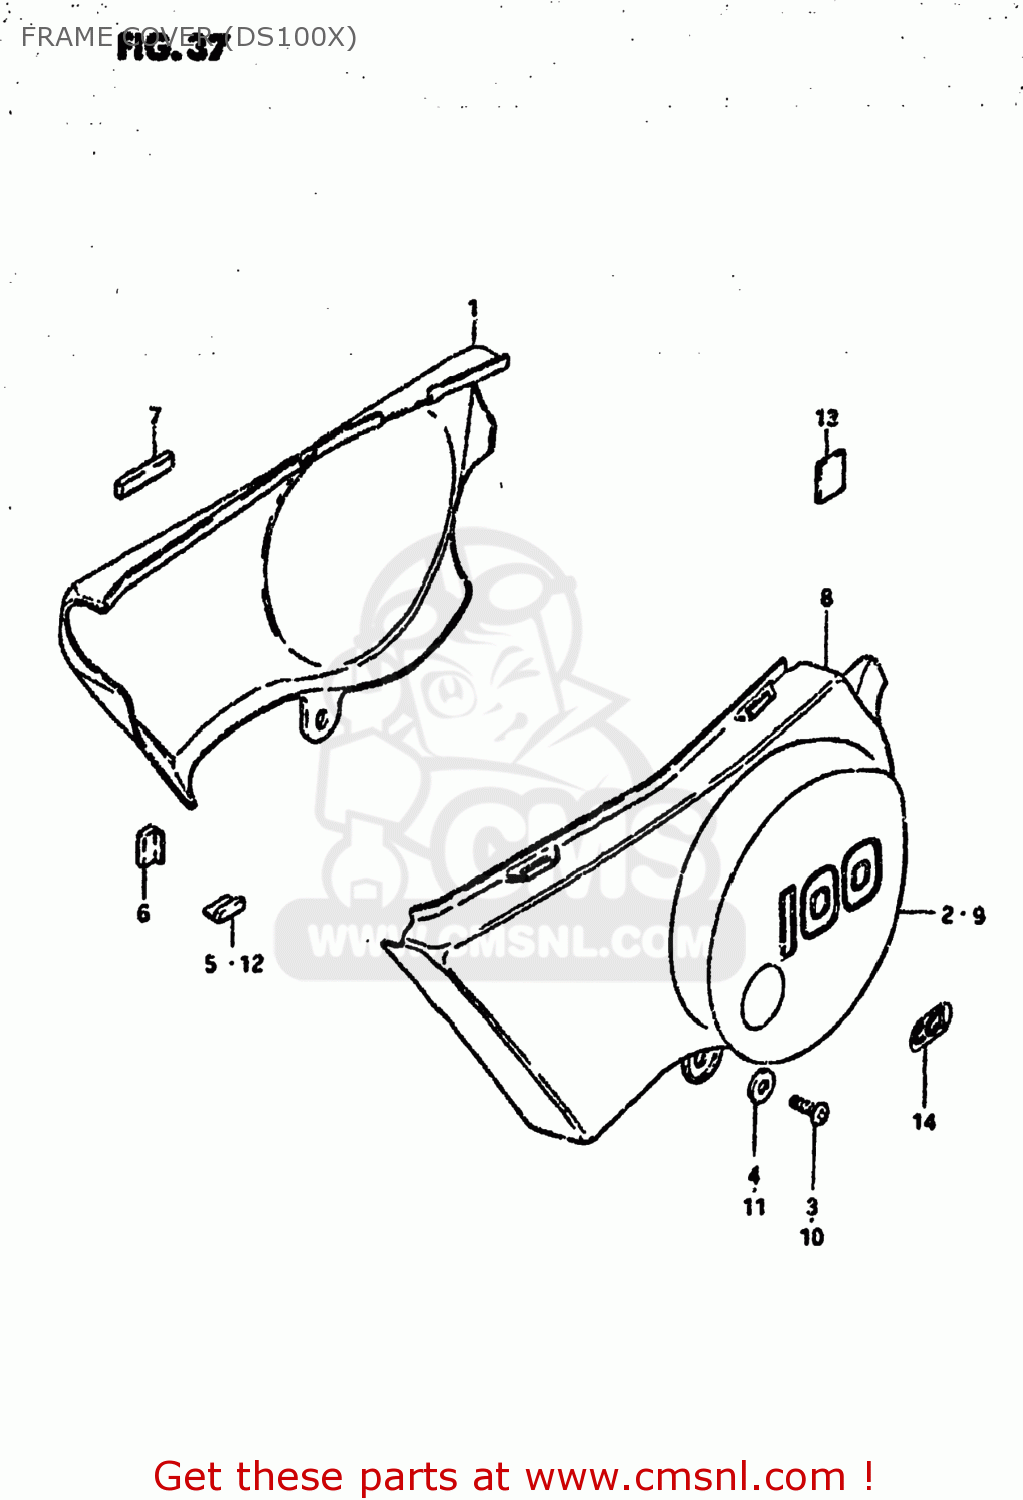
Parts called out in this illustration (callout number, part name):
1	COVER,FRAME,RIGHT
2	EMBLEM
3	SCREW
4	WASHER
5	CUSHION,FRAME COVER
6	CUSHION,FRAME COVER
7	CUSHION,FRAME COVER
8	COVER,FRAME,LEFT
9	EMBLEM,FRAME COVER
10	SCREW
11	WASHER
12	CUSHION,FRAME COVER
13	PROTECTOR(170X95X3.0)
14	EMBLEM,CCIS
